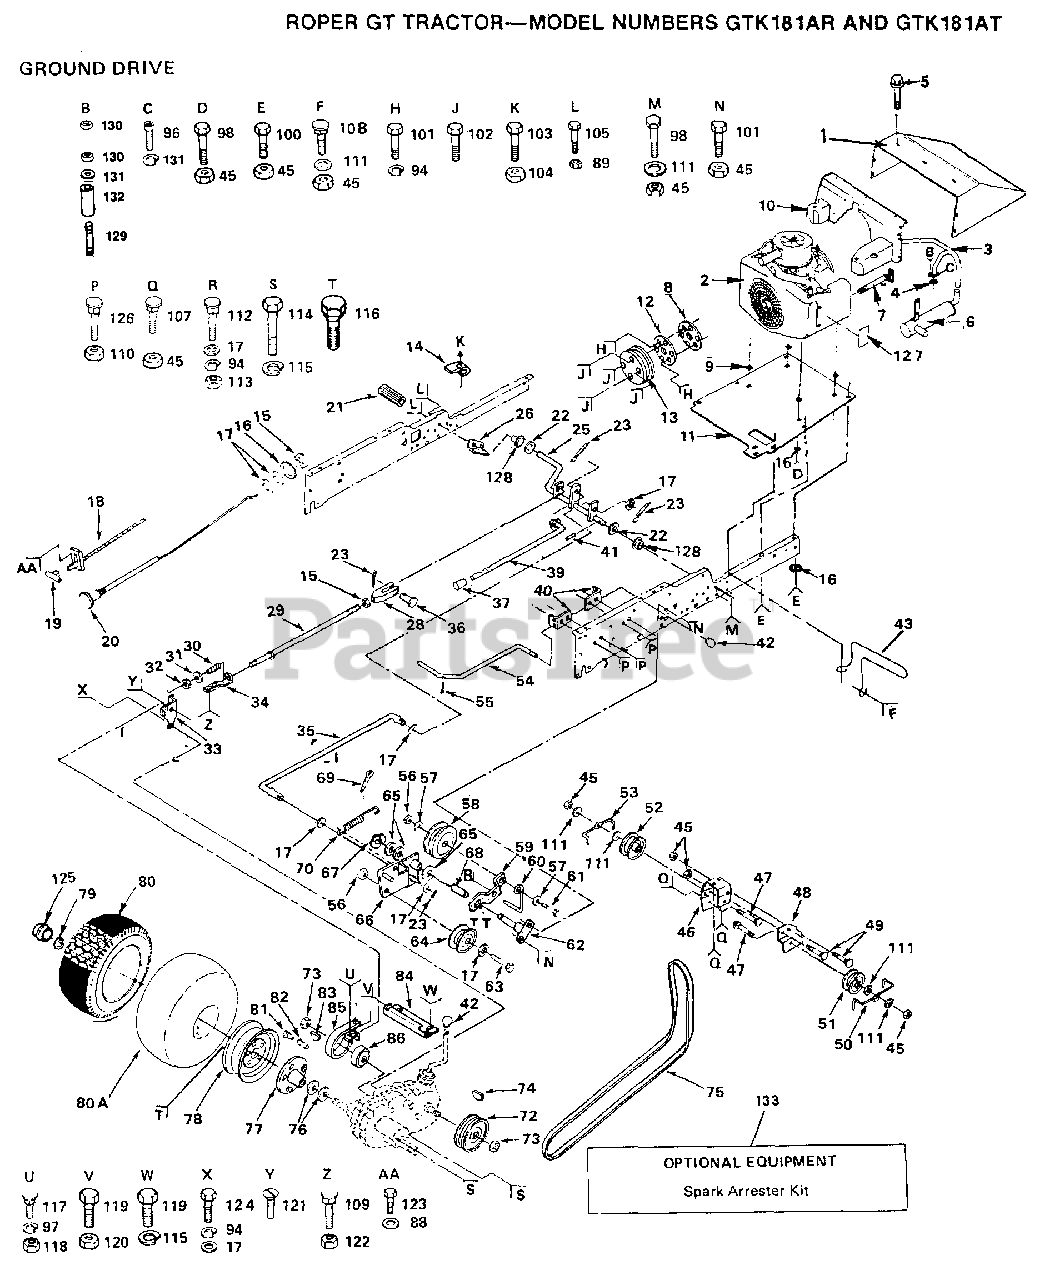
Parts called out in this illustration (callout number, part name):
2	ENGINE - 18 H.P. SPEC. #24573
3	EXHAUST TUBE T
7	DRAIN VALVE
8	CHAFF GUARD T
11	"ENG. T, BASE"
12	ADAPTER T
14	ACT-SWITCH T
16	LOCKWASHER
17	WASHER
21	PEDAL COVER T
25	SHAFT ASSY GT
26	BRKT SWITCH GT
28	YOKE GTV
29	BRAKE ROD T
30	SPRING T
31	WASHER
33	BRAKE BRKT ASSY T
34	GUIDE ROD T
35	ROD CLUTCH GTV
36	CLEVIS PIN T
37	PLUNGER CAP T
40	ROD BRACKET GT
41	ROLL PIN STD
43	GUARD MUFFLER HYT
47	BOLT
49	BOLT
50	BELT GUARD T
51	IDLER-FLAT T
52	PULLEY V IDLR GTV
53	BELT GUARD GT
54	ROD SHIFT GTV
56	LOCKNUT
57	WASHER
60	BELT RETAINER GT
62	BRACKET ASSY GTV
64	IDLER PULLEY T
65	WASHER T
66	CLUTCH BRACKET GT
67	KLIP RING
68	"LY, BEARING"
69	COTTER PIN
70	SPRING GTV
72	PULLEY GT
73	NUT STD
75	BELT-V.98.5.GD.DV
76	WASHER T
79	KLIP RING
80A	TUBE.23X8/10-12
81	VALVE CAP
82	VALVE STEM LT
86	BRAKE DRUM T
88	WASHER
93	BOLT
94	LOCKWASHER
95	WASHER
96	SCREW
97	LOCKWASHER
98	BOLT
99	LOCKWASHER.5/16.E
101	BOLT
103	SCREW
105	BOLT LT
107	BOLT
108	BOLT.3/8-14X1.25
111	WASHER GT
113	NUT.HEX.3/8-16UNC
114	BOLT
115	LOCKWASHER
117	BOLT T
119	BOLT
120	NUT GTV
121	SCREW
123	SCREW
125	CAP-HUB GT
126	BOLT
128	NYLINER T
130	NUT - 5/16-18
133	SPARK ARREST KIT
